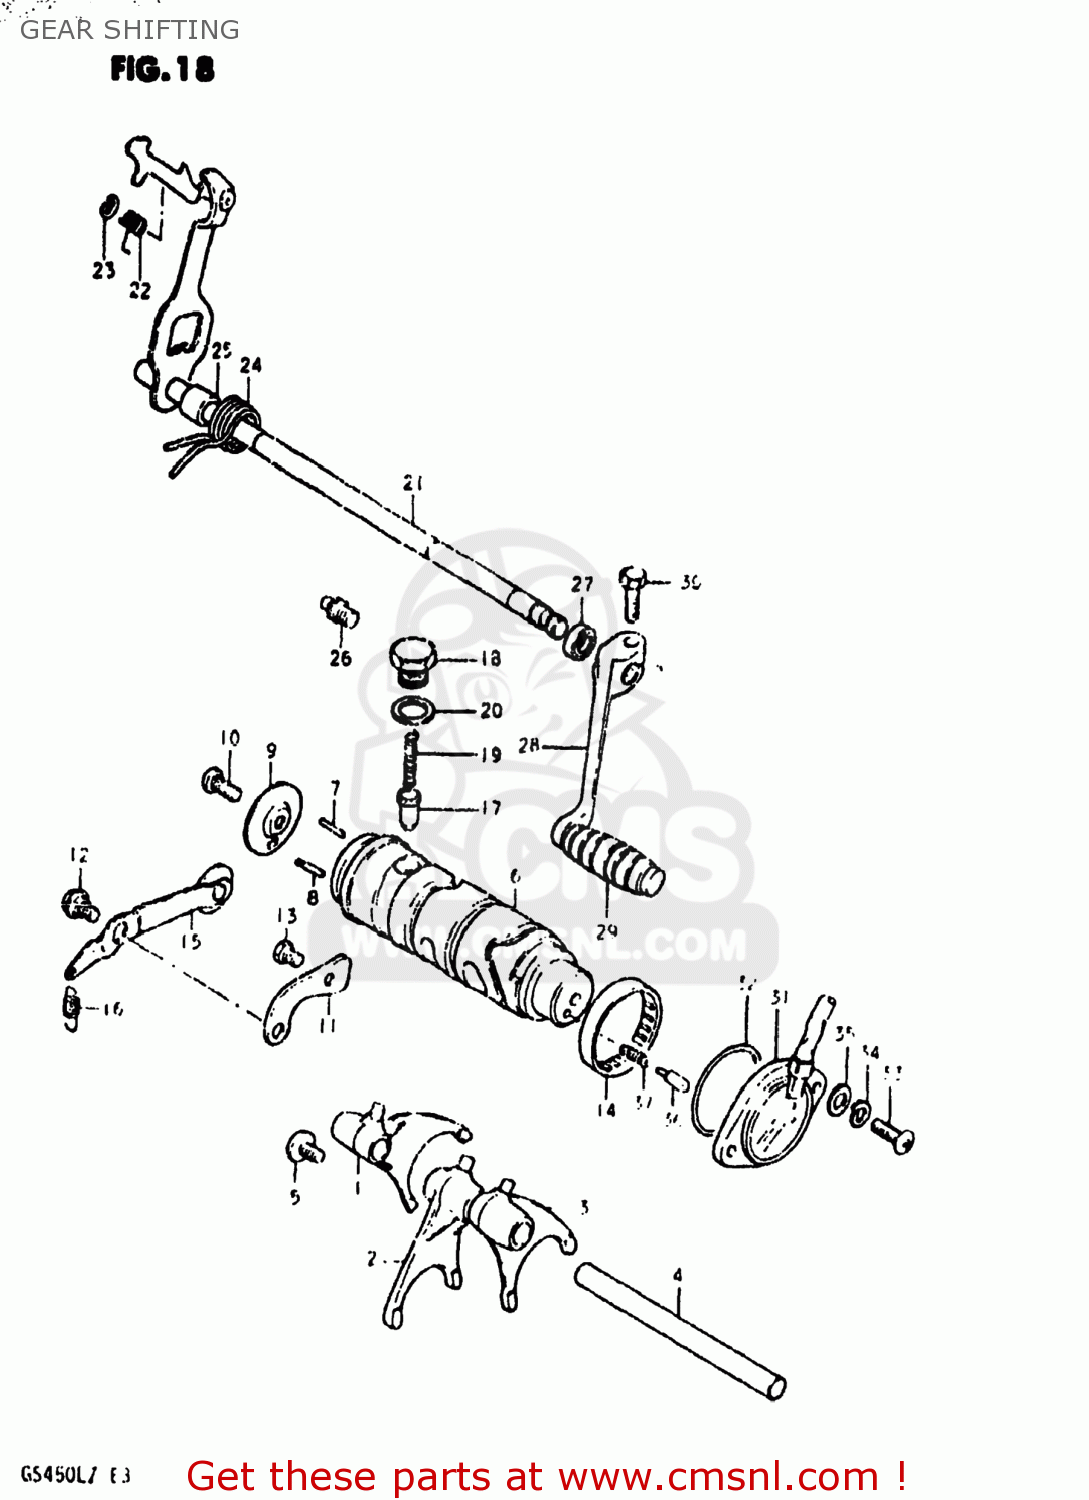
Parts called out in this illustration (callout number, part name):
1	FORK,GEAR SHIFT NO.1
2	FORK,GEAR SHIFT NO.2
3	FORK,GEAR SHIFT NO.2
4	SHAFT,GEAR SHIFT FORK
5	SCREW
6	CAM,GEAR SHIFT
7	PIN(4X18.5)
8	PIN
9	RETAINER,GEAR SHIFT CAM DR PIN
10	SCREW
11	GUIDE,GEAR SHIFTING CABLE
12	BOLT
13	BOLT, UPPER
14	BEARING(40X47X12)
15	STOPPER,GEAR SHIFT CAM NO.1
16	SPRING
17	STOPPER,GEAR SHIFT CAM NO.2
18	HOLDER,GEAR SHIFT CAM STOP SPR
19	SPRING
20	GASKET(14X19.2X2) (NAS)
21	SHAFT,GEAR SHIFT
22	SPRING
23	E RING
24	SPRING
25	SPACER(12X20X15.3)
26	STOPPER,GEAR SHIFT CAM
27	OIL SEAL
28	LEVER ASSEMBLY,GEAR SHIFTING
29	RUBBER,GEAR SHIFT PEDAL
30	BOLT
31	BASE ASSEMBLY,NEUTRAL SWITCH TERMINAL
32	O-RING (D:2.4 ID:26.2)
33	SCREW 5X20
34	LOCK WASHER
35	WASHER
36	PIN(5X15.5)
37	SPRING
